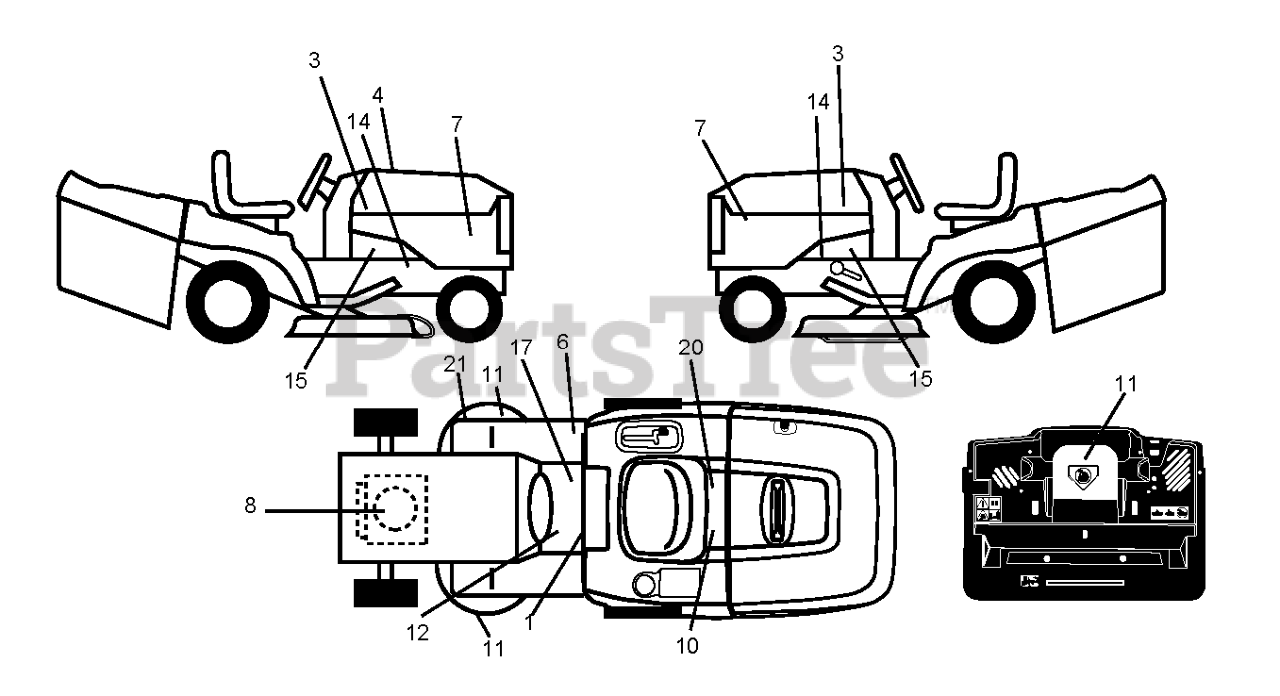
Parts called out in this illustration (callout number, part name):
1	LABEL
3	RP.DECAL.BADGE.170MM.TEXTLOGO
6	Decal, Fender 100 DB/CE
8	DECAL
10	DECAL BTRY SYMBOLS
11	DECAL.INTERNATIONL.CUTFINGER
12	DECAL
17	DECAL PARK BRAKE
20	DECAL.BYPASS.FENDER.CRD.LT.YT
